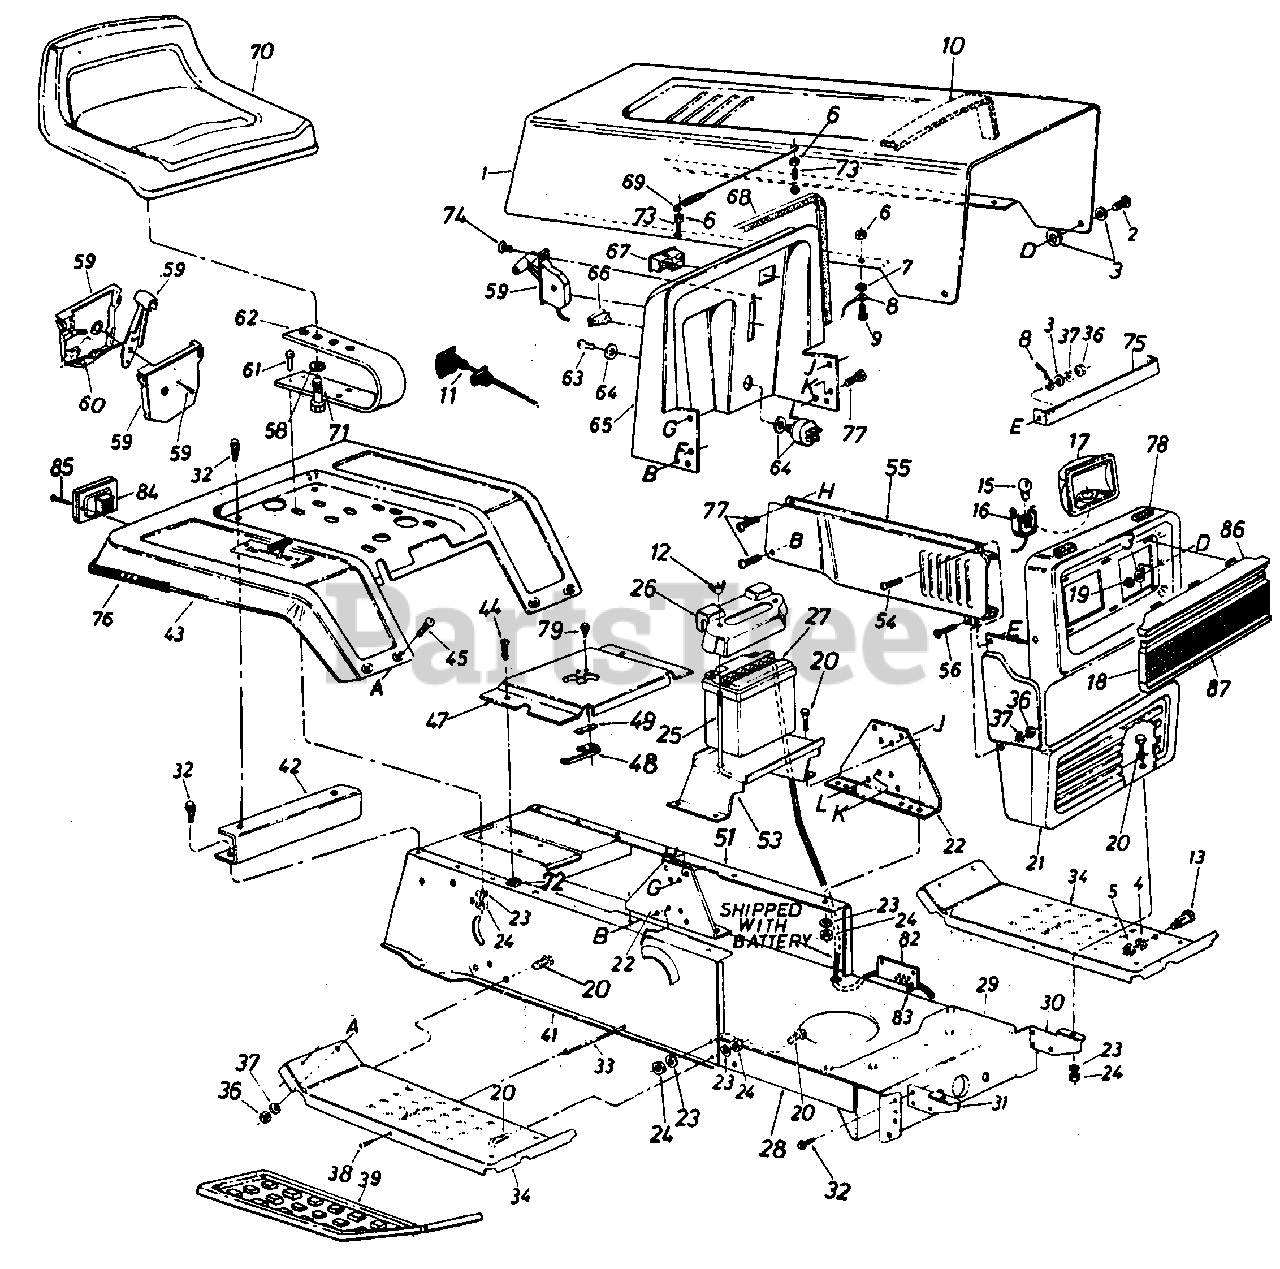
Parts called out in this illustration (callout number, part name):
1	Hood
2	Hex Scr. 1/4-20 x .62" Lg.
3	Fl-Wash. .296" I.D. x .62" O.D.
4	L-Wash. 3/8" I.D.
5	Hex Nut 3/8-16 Thd.
6	Hex Sems Nut #10-24 Thd.
7	Fl-Wash. .203" I.D. x .41" O.D. x .040
8	Hood Stop
9	Truss Hd. Scr. #10-24 x 1/2" Lg.
10	PVC Foam
11	Choke Control 44.0" Lg.
12	Wing Nut '/4-20 Thd.
13	Shld. Bolt .50" Dia. x .84
15	Lamp
16	Twist Lock Lamp Socket
17	Headlight Housing
18	Headlight Bezel
19	Hex L-Nut 1/4-20 Thd.
20	Hex Bolt 5/16-18 x .75" Lg.
23	L-Wash. 5/16" I.D.
24	Hex Nut 5/16-18 Thd.
25	Battery Hold Down Rod
26	Battery Cover
27	12 Volt Battery
28	Lower Frame
29	Front Pivot Brk't.
30	Grille Mount Brk't. L.H.
33	Running Board Rod
34	Running Board
36	Hex Nut 1/4-20 Thd.
37	L-Wash. 1/4" I.D.
38	Truss Mach. Scr. 5/16-18 x .75" Lg.
39	Rubber Foot Pad
41	R.H. Side Frame
42	Fender Mount Brace
43	Rear Fender
44	Truss Mach. Tap Scr. #10 x .50" Lg.
45	Carriage Bolt 1/4-20 x .50" Lg.
47	Transmission Panel
48	Reverse Safety Switch
49	Insulator Nut Plate
51	L.H. Side Frame
53	Battery Bracket
54	Truss Hd. Scr. 1/4-20 x .75" Lg.
56	Truss Mach. Scr. 1/4-20 x .50" Lg.
58	L-Wash. 1/2" I.D.
59	Throttle Control Box Ass'y.
60	Throttle Control Wire 35"
61	Hex Bolt 5/16-18 x 1.0"
62	Seat Spring 5.5" High
63	Ignition Key
64	Ignition Switch
65	Dash Panel
66	Light Switch
67	Ammeter
68	Trim Strip 27"
69	Hood Spring
70	Seat Ass'y.
71	Hex Bolt 1/2-13 x 1.0" Lg.
72	Speed Nut #10Z
73	Hex Scr. #10-24 x 1.0" Lg.
74	Truss Mach. AB-Tap Scr. #10 x .5" Lg.
75	Tie Strap Grille/Side Panel
76	Trim Strip 81"
77	Hex Wash. Hd. Tap Scr. 1/4 x.75" Lg.
78	Foam Strip 3/8 x 1-1/8 x 1-1/2" Lg.
79	Hex Wash. Hd. AB-Tap Scr. #8 x .50" Lg.
82	Brake Cable Bracket
83	Cable Tie
84	Taillight
85	Truss AB-Tap Scr. #6 x .62"
86	Upper Frame For Bezel
87	Lower Frame For Bezel
